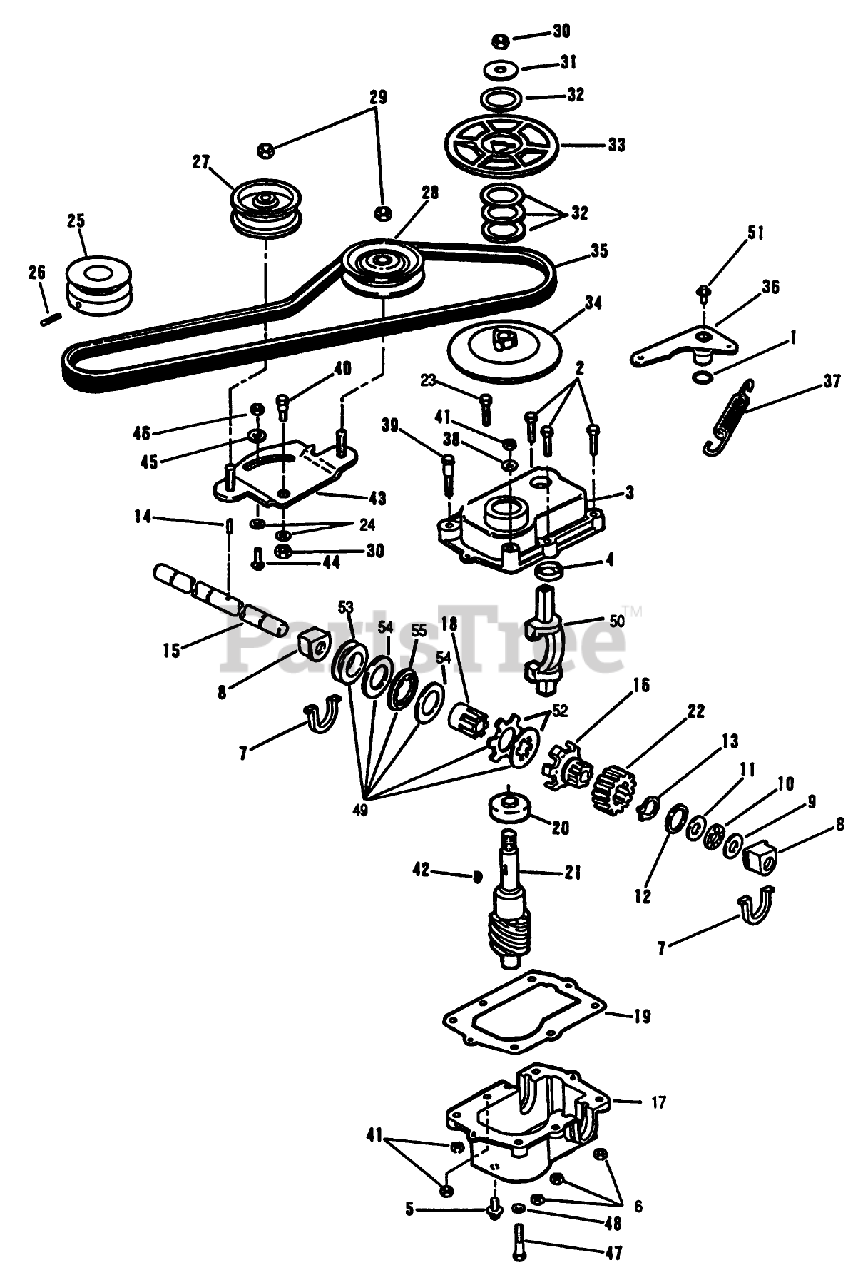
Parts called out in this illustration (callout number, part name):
4	GUIDE ELCO
6	LOCKNUT E
8	BEARING & SEAL AY (12)
9	THRUST WASHER
11	WASHER-THRUST
13	RET RING
14	PIN DRIVE LOCK
18	DRIVER BROCKWAY
19	GASKET HOOSIER
20	BEARING-BALL
22	WORM WHEEL
24	WASHER S
25	PULLEY F
26	SET SCREW F
27	PULLEY NEWHAM IND *B
28	IDLER NEW HAM IND
29	NUT-JAM, LOCKING
30	LOCKNUT
33	PULLEY UPPER PL
34	PULLEY LOWER PL
36	SHIFT ARM & HUB AY
41	LOCKNUT E
42	KEY GALGER
46	NUT-LOCK F
50	FORK SHIFT
51	SCREW SEMS SM
55	SVC LTR#28,ORD 684684
